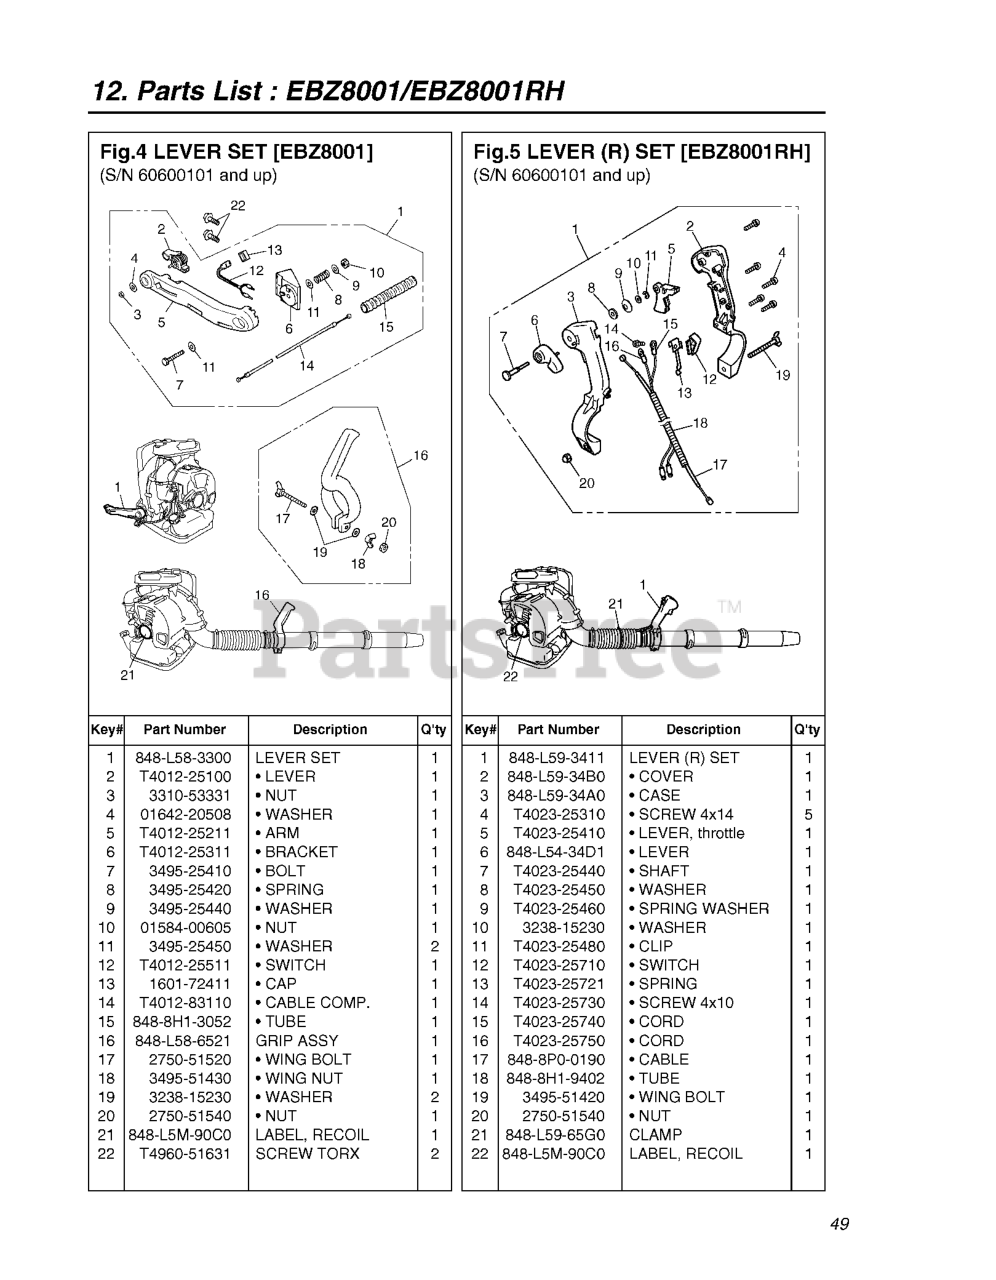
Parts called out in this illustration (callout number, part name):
4	WASHER
5	ARM
9	WASHER Z349525440
13	CAP SWITCH
14	RP_CABLE COMP
16	GRIP ASSY
17	WING BOLT
18	WING NUT
19	WASHER
